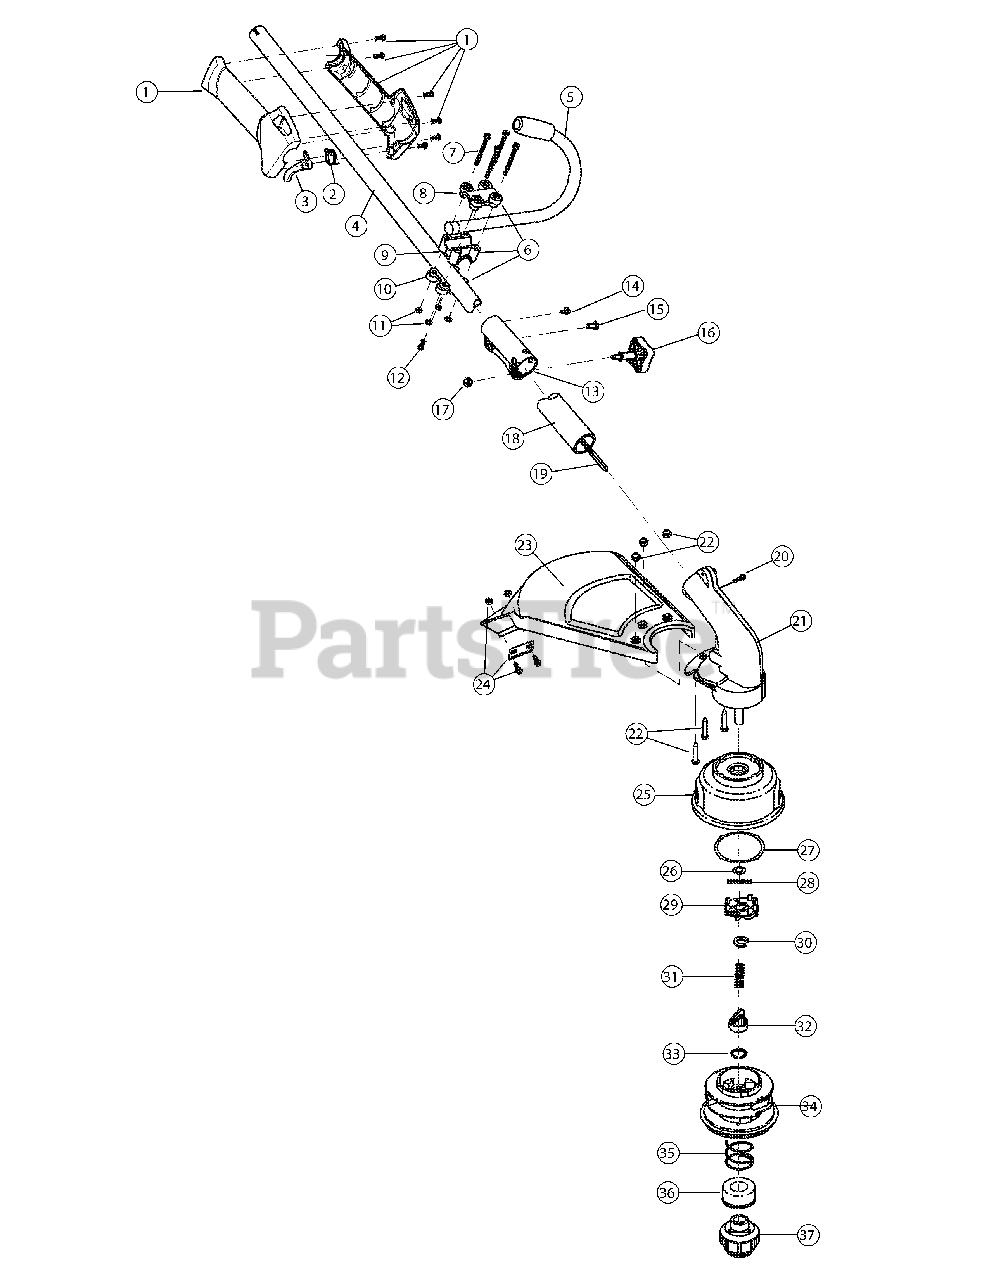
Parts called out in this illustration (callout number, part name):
1	Throttle HousingAssembly
2	Throttle Trigger Spring
3	Throttle Trigger
4	Upper Drive Shaft Housing Assembly
5	J-Handle Assembly
6	Handle Bracket Assembly
8	Upper Handle Clamp
9	Middle Handle Clamp
10	Lower Handle Clamp
12	Anti-Rotation Screw
13	Split Boom Coupler
16	Adjustment Knob
17	Knob Retaining Nut
18	Lower Drive Shaft Housing Assembly
19	Lower Flexible Drive Shaft
20	Anti-Rotation Screw
21	Gearbox Assembly
22	Shield Mounting Hardware
23	Shield Assembly
24	Blade Assembly
25	Outer Spool Assembly
26	Retainer
27	Thrust Washer
28	Small Spring
29	Slider
32	Plunger
34	Inner Reel
35	Large Spring
36	Foam Seal
37	Bump Head Knob Assembly
